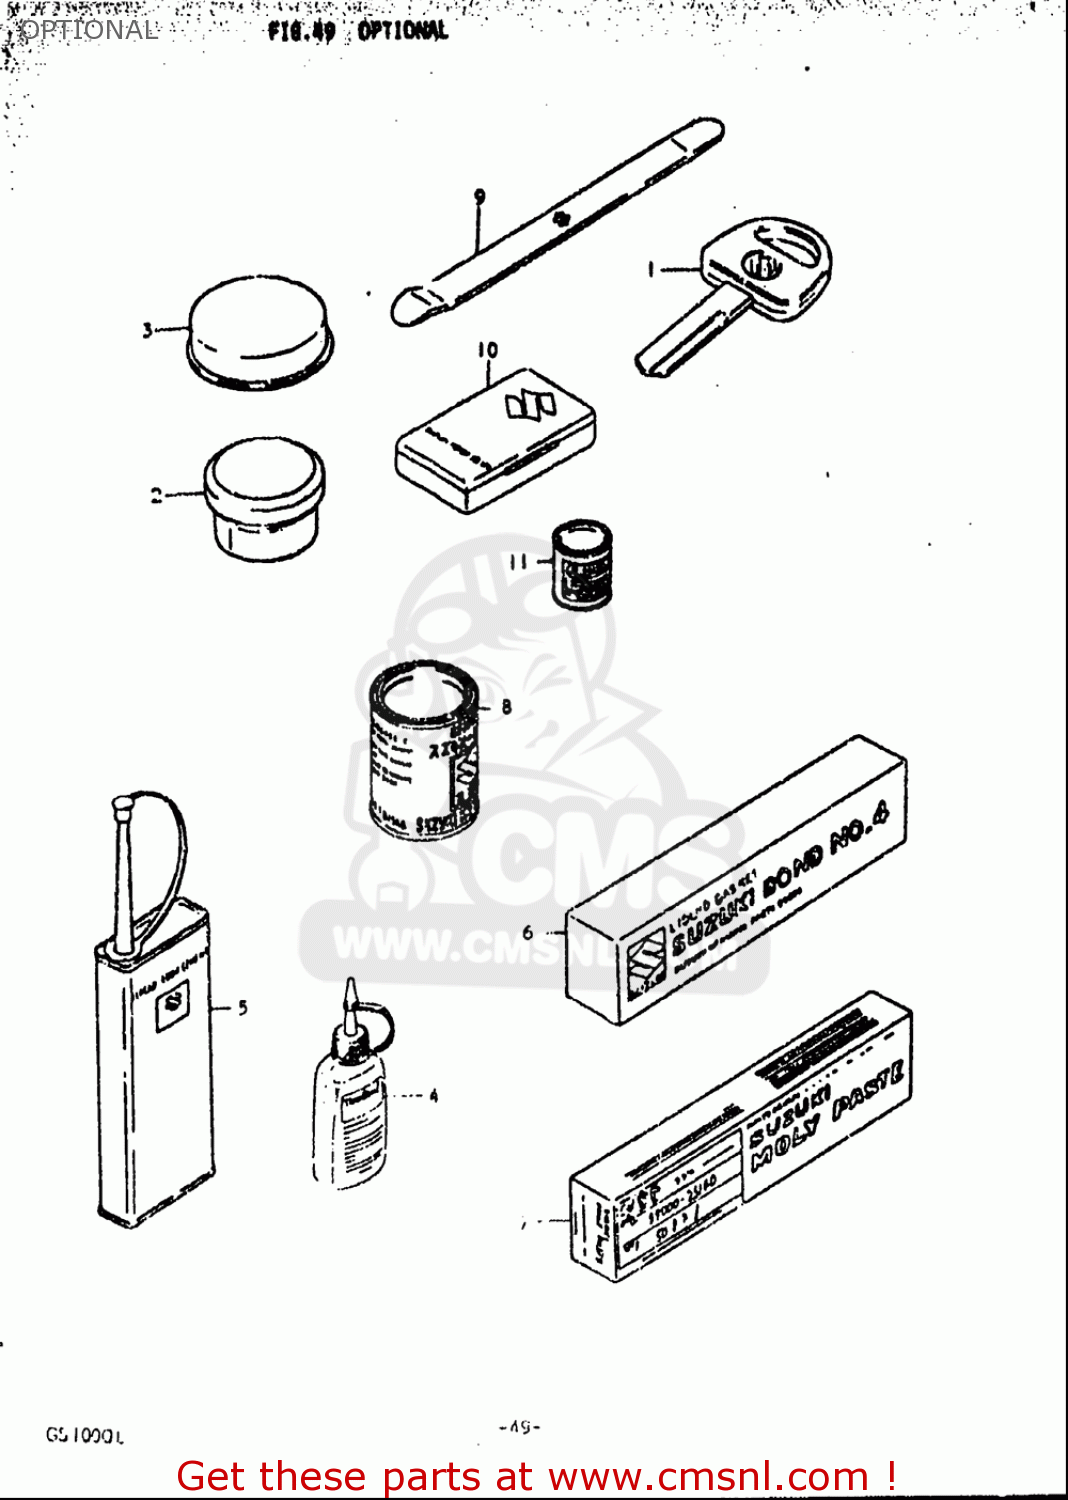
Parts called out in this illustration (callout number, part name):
1	KEY,BLANK
2	GREASE,PBC FOR BRK PAD 20G
3	GREASE,SILICON 20G
4	THREAD LOCK NO.1303B PURPL 50G
5	THREAD LOCK NO.1401 CLEAR 200G
6	BOND 1104
7	SUZUKI MOLY PASTE
8	GREASE(C)EP2 LITHIUM 150G
9	LEVER,TIRE
12	GASKET SET
